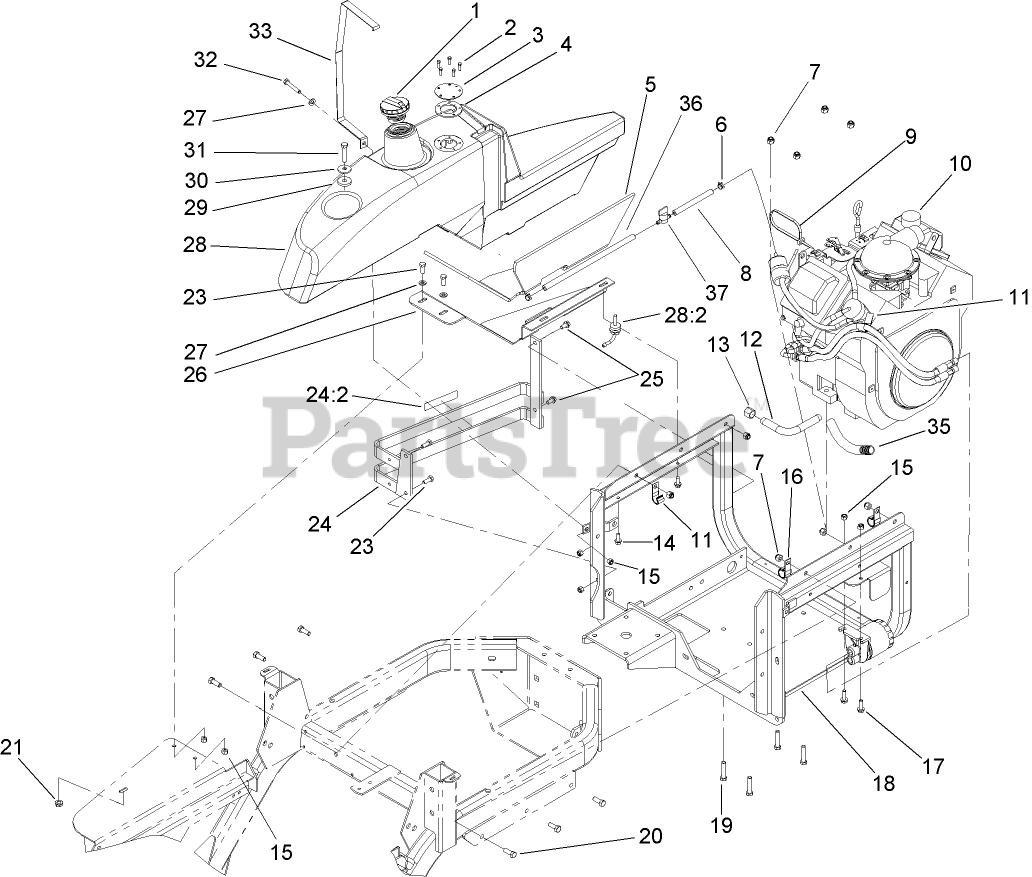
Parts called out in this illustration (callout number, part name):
1	CAP-FUEL
2	SCREW-PPH
3	COVER-OPENING, FUEL TANK
4	GASKET
5	FOAM-TANK, FUEL
6	CLAMP-HOSE
7	NUT-LOCK, NI
8	HOSE-FUEL
9	TIE-CABLE
11	CLIP
12	TUBE-DRAIN, OIL
13	CAP-PIPE
14	SCREW-HWHTF
15	NUT-LOCK, NI
16	CLAMP-J
17	SCREW-HHF
18	ENGINE FRAME ASM
19	SCREW-HH
20	SCREW-HH
21	NUT-HHF, WHIZ
23	SCREW-HH
24	BUMPER ASM
24:2	DECAL-HOT SURFACE
25	SCREW-HWHTF
26	PLATE-SUPPORT, TANK
27	WASHER-PLAIN
28	FUEL TANK ASM
28:2	FITTING-FUEL, BULKHEAD
29	BUSHING-FLANGE
30	WASHER
31	SCREW-HH
32	SCREW-HH
33	STRAP-TANK, FUEL
35	TUBE-CONVOLUTED
36	HOSE-FUEL
37	VALVE-FUEL
